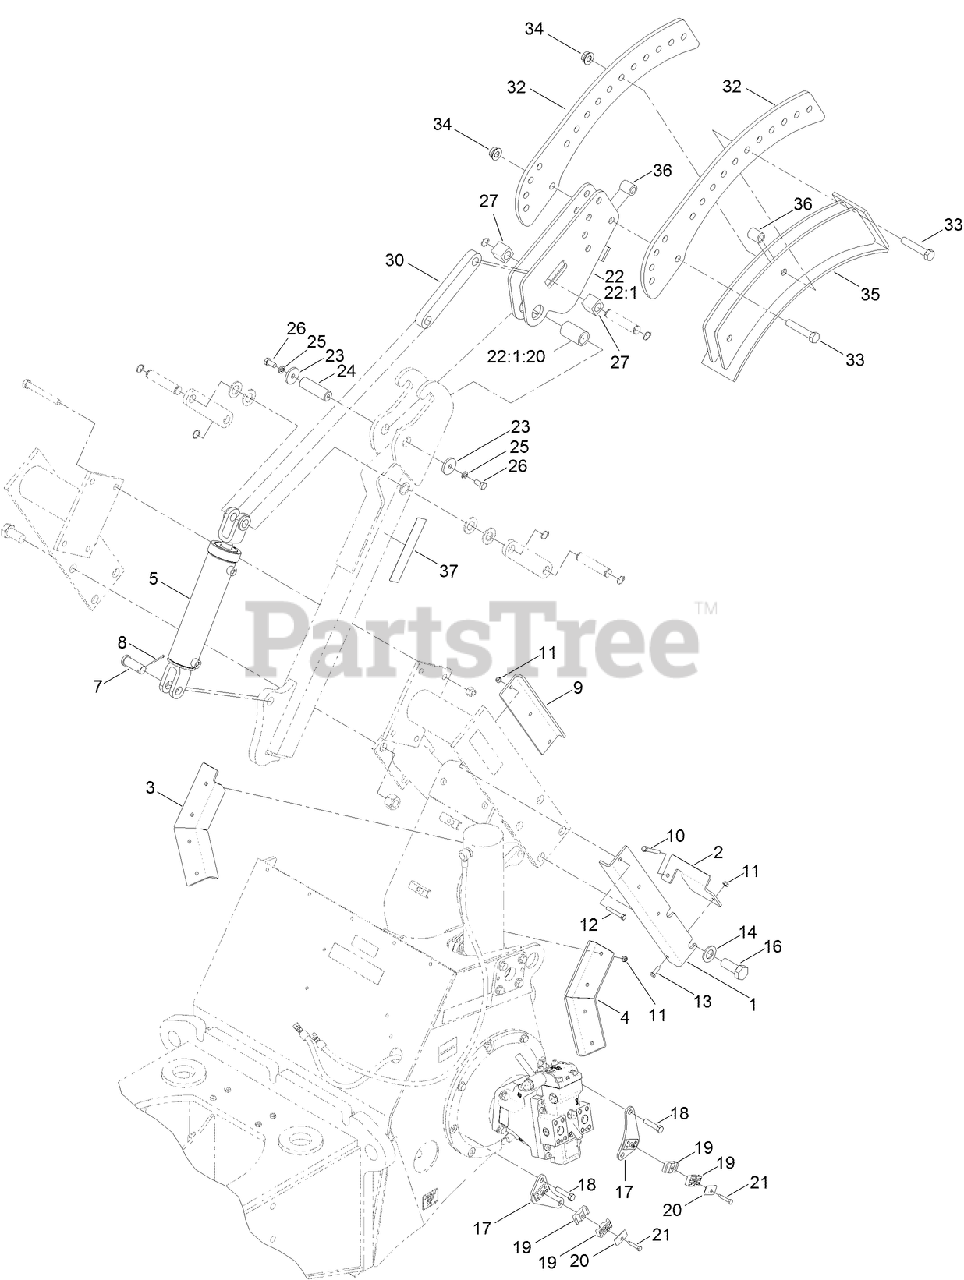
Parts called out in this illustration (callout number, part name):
1	ANGLE-CONDUIT
2	ANGLE-TIE
3	ANGLE-LOWER CONDUIT
4	ANGLE-LOWER CONDUIT
5	CYLINDER-HYDRAULIC
7	PIN-CLEVIS
8	PIN-COTTER
9	ANGLE-CONDUIT
10	SCREW-HH
11	NUT-HEX
12	SCREW-HH
13	SCREW-HH
17	MOUNT-CLAMP, HOSE
18	SCREW-HH
19	CLAMP-TUBE
20	COVERPLATE
22	PIVOT-CRUMBER
22:1	PIVOT-CRUMBER
22:1:20	TUBE-PIVOT, CRUMBER
23	WASHER-FLAT
24	PIN-PIVOT, CRUMBER PIVOT
25	WASHER-LOCK
26	SCREW-HH
27	BLOCK-SLIDE - SQ. BAR
30	LINK-CRUMBER PUSH
32	PLATE-CRUMBER CONNECTOR
34	NUT-HEX FLANGE
35	SHOE-CRUMBER - BLADE MOUNT
36	SPACER
37	DECAL-DANGER, ENTANGLEMENT
